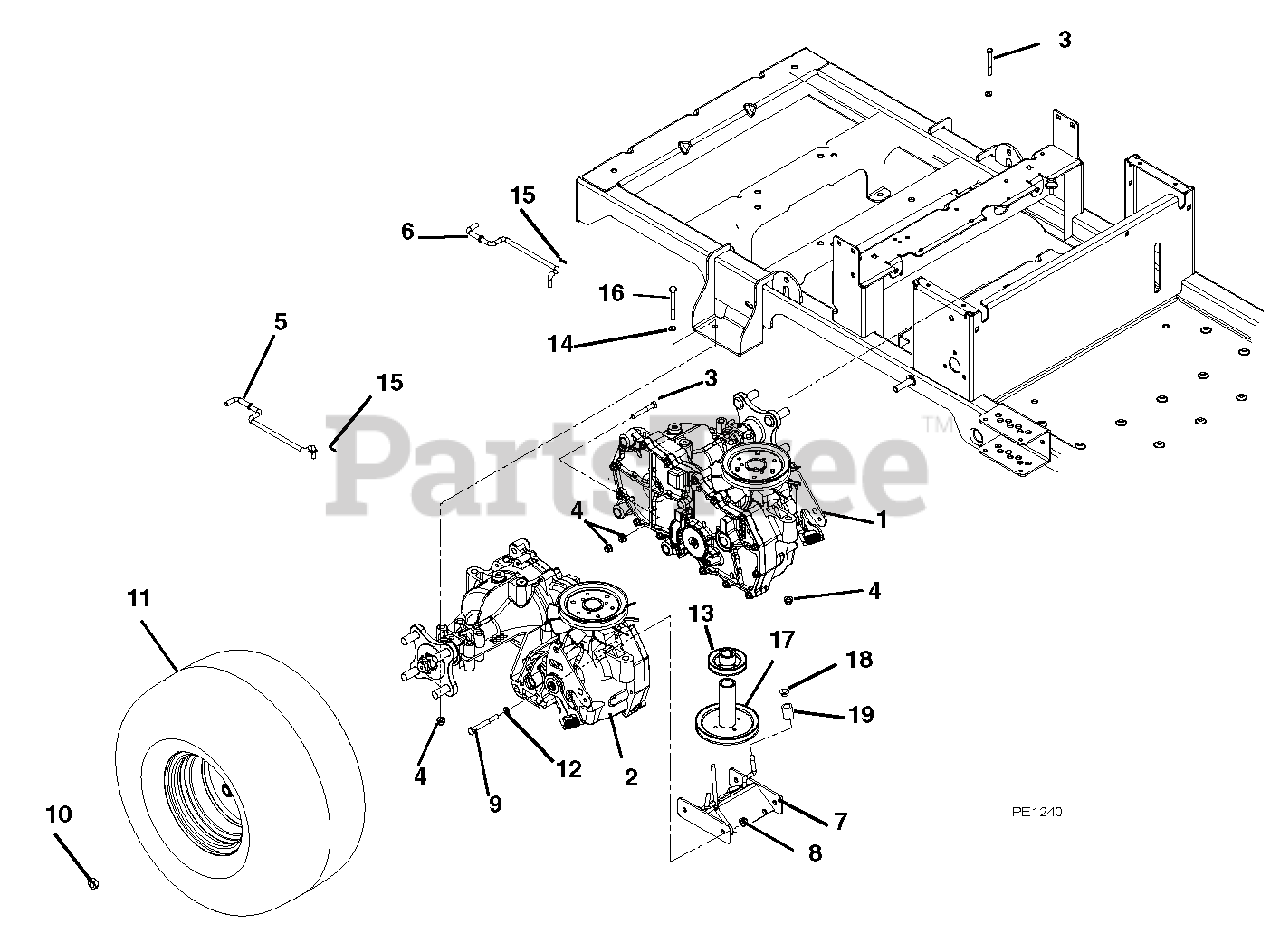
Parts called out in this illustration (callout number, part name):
1	Transaxle, EZT Short Left Hand
2	Transaxle, EZT Short Right Hand
3	Bolt, Hex .31-18 x 2.25 Grade 5
4	Nut 5/16-18 Flange Nyloc
5	Dump Valve (RH)
6	Dump Valve (LH)
7	Weldment, Transaxle Brace
8	Nut, Nyloc Flange .38-16
9	Bolt-Hex .38-16 x 2.50 Grade 5
10	Nut, Wheel .50-20 13/16
11	Tire/Wheel Assembly, 18 x 6.5-8 Offset
12	Washer, Flat Steel .406 x 1.00 x .188
13	Weldment, Sheave Ground Drive
14	Washer-Flat-Steel .38 x .875 x .083
15	Pin-Hair-Internal .06 x .18 x .77
16	Bolt, Hex .31-18 x 2.75
17	Weldment, Sheave PTO Drive
18	Nut-Push .312
19	Spacer, .75 x .335 x .75
